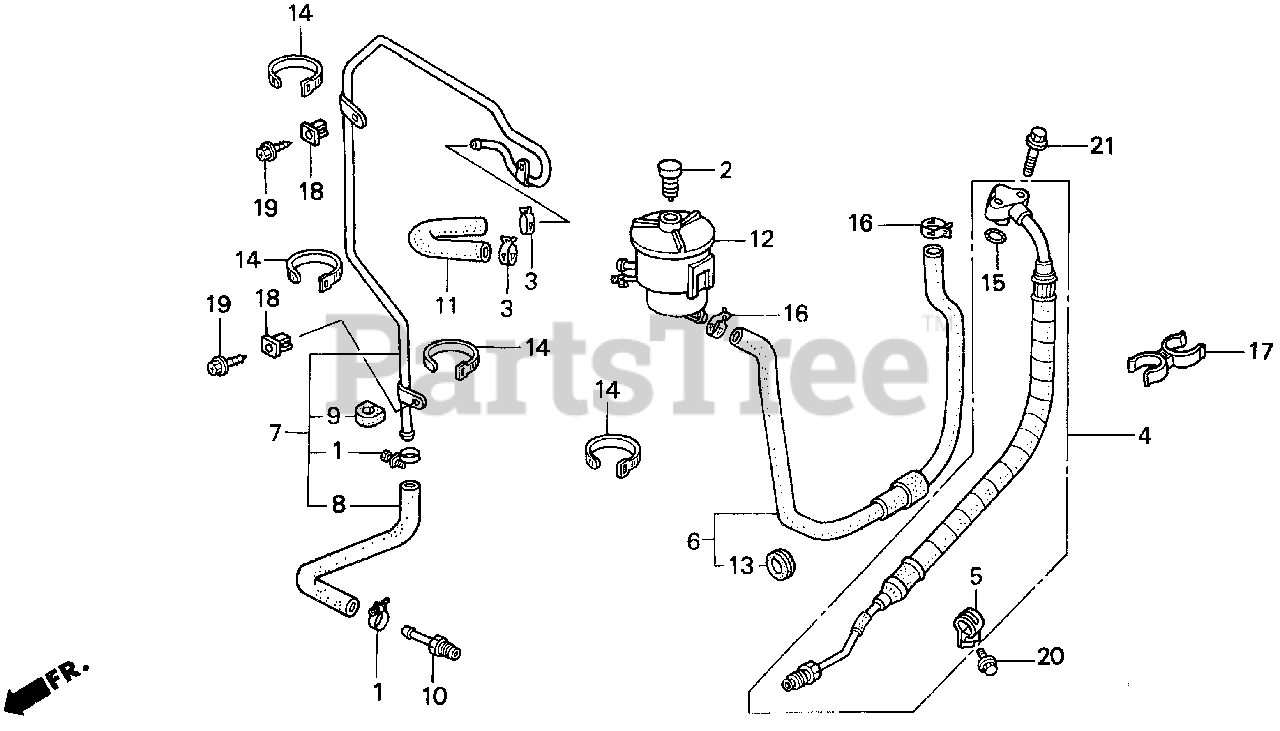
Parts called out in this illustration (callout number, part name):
1	CLIP, TUBE
2	CAP, OIL TANK
3	CLAMP D (15.5MM)
4	HOSE, POWER STEERING FEED
5	CLAMP, POWER STEERING FEED HOSE
6	TUBE, POWER STEERING SUCTION
7	COOLER ASSY., POWER STEERING OIL
8	TUBE, RETURN
9	OIL SEAL, POWER STEERING COOLER
10	PIPE, POWER STEERING RETURN
11	TUBE, OIL COOLER RETURN
12	TANK ASSY., POWER STEERING OIL
13	RUBBER, MIRROR SETTING
14	BAND, CABLE (120MM) (BLACK)
15	O-RING (8.8X1.9)
16	CLAMP D (19MM)
17	CLIP, METER CABLE
18	GROMMET, SCREW (6MM)
19	SCREW, TAPPING (6X12)
20	BOLT, FLANGE (6X14)
21	BOLT, FLANGE (6X30)
